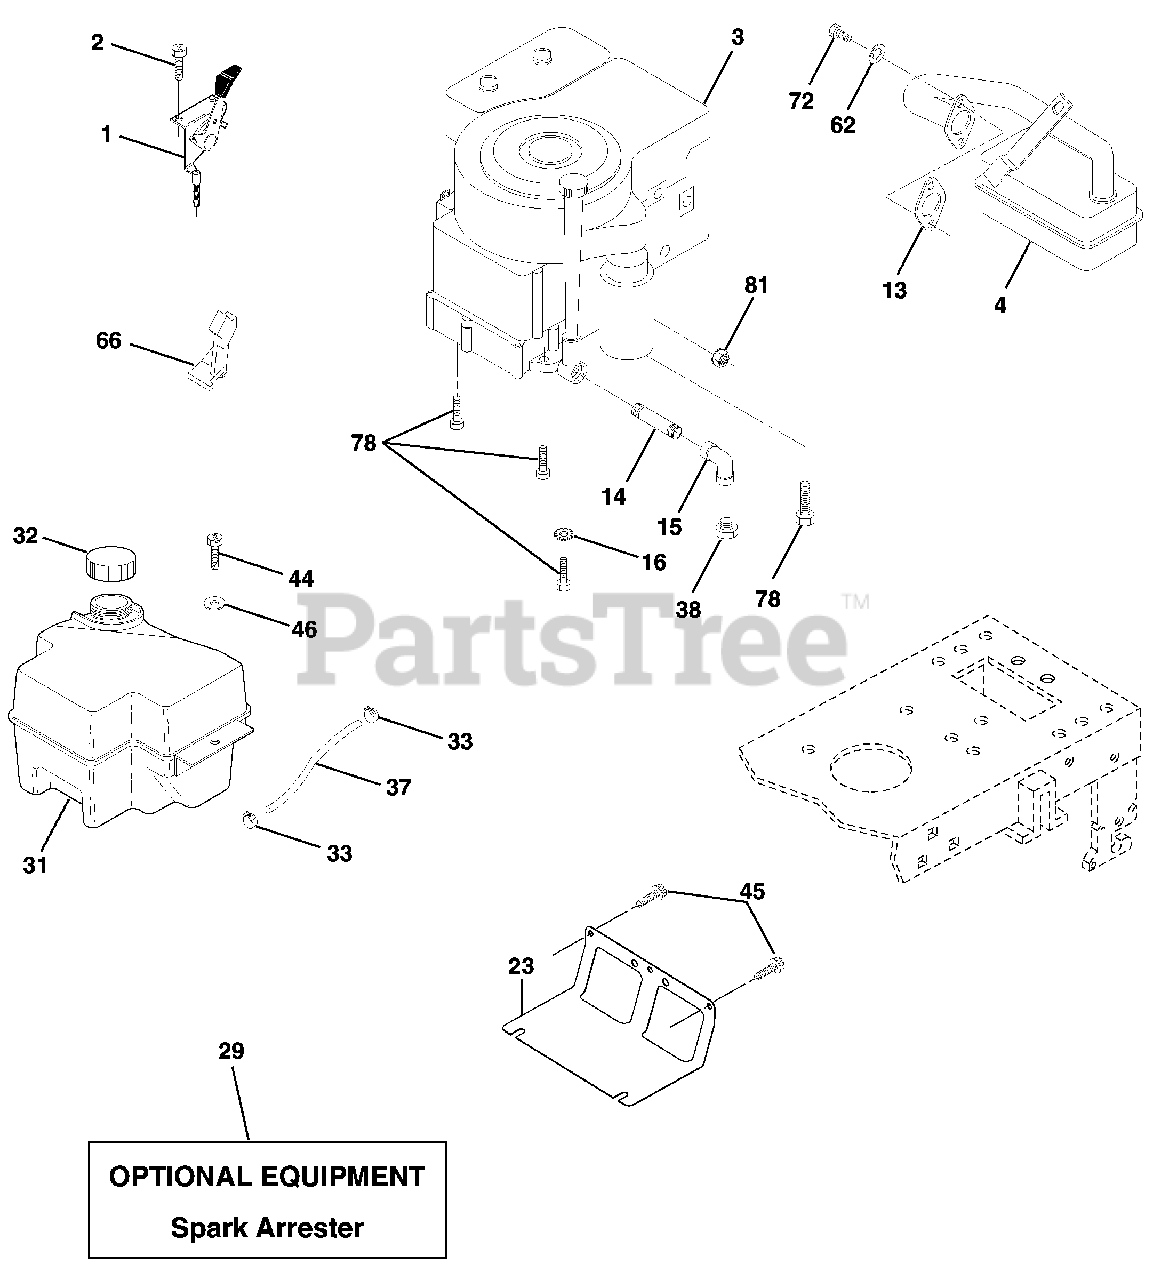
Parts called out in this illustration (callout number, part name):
1	Control Throt /Ch Lh
2	Screw Hex Thd Cut 1/4-20x5/8 T
4	Muffler Exhaust B&S Lt
13	Gasket 1 313 Id Tin Plated
14	Nipple Pipe 3/8 Npt X 3"
15	Elbow Std 90 Degree 3/8-18 Npt
16	Washer Lock Ext Tooth 3/8
23	Shield Browning/Debris Guard
29	Arrestor Spark
31	Tank Fuel 2.00 Fr
32	Cap Asm Fule Top Vent N/Lany
33	Clamp Hose Blk
37	Line Fuel 20"
38	Plug Oil Drain
44	Screw Hexwsh Thdrol 1/4-20 x 3/4
45	Screw Hexwsh Thdr 3/8-16 x 3/4
46	Washer 9/32 X 7/8 X 16ga
62	Washer Lock Hvy Hlcl Spr 5/16
66	Stop Throttle 3000 Rpm
72	Screw Hexhd Cap 5/16-18 x 3/4
78	Screw 3/8-16x1-1/4
81	Nut Keps 1/4-20 Unc
